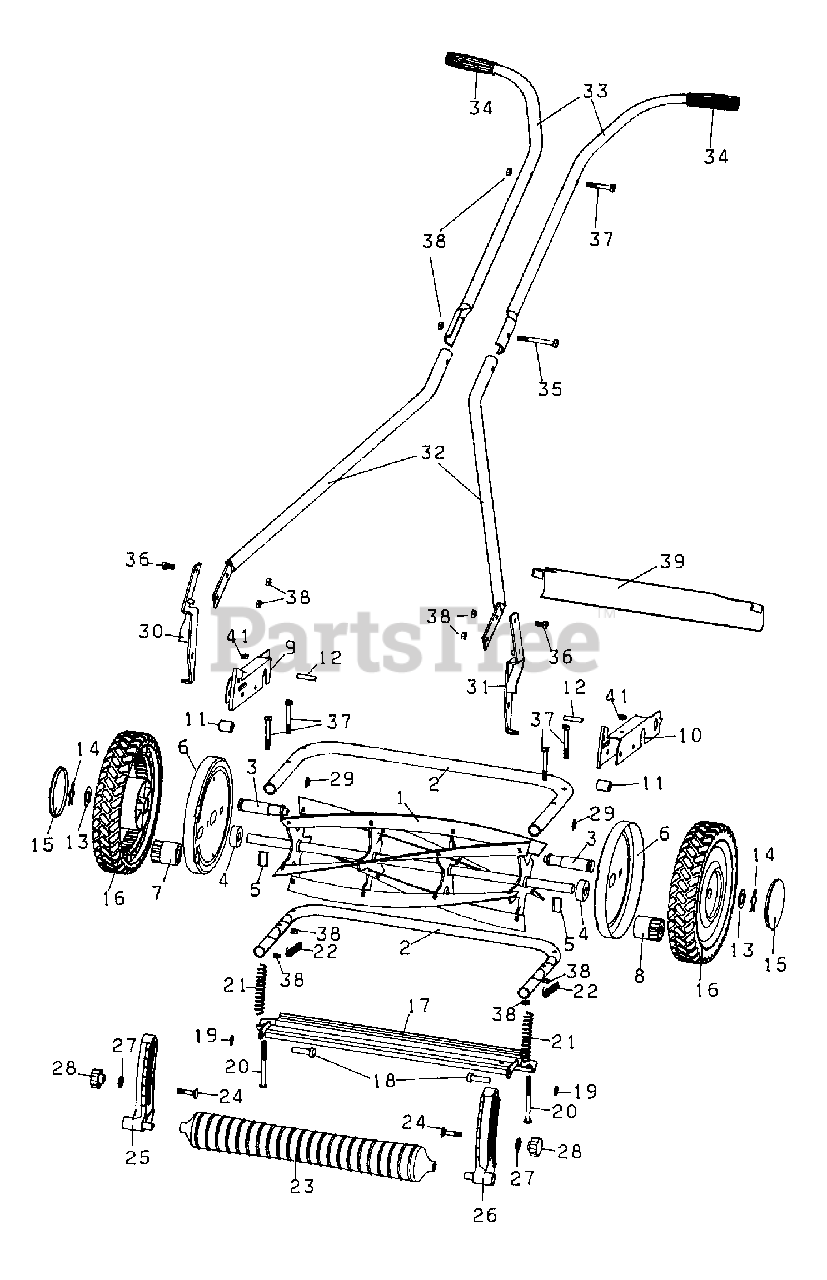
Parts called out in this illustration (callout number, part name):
1	CUTTING REEL
4	BEARING
12	P/N NOT AVAILABLE
15	HUBCAP
16	WHEEL
19	LOCKING WASHER
22	P/N NOT AVAILABLE
23	ROLLER 4/40
25	HEIGHT GAUGE
26	HEIGHT GAUGE
27	WASHER
29	P/N NOT AVAILABLE
32	LOWER HANDLE
34	HANDLE
35	SCREW M6X50
38	LOCKNUT M6
39	P/N NOT AVAILABLE
